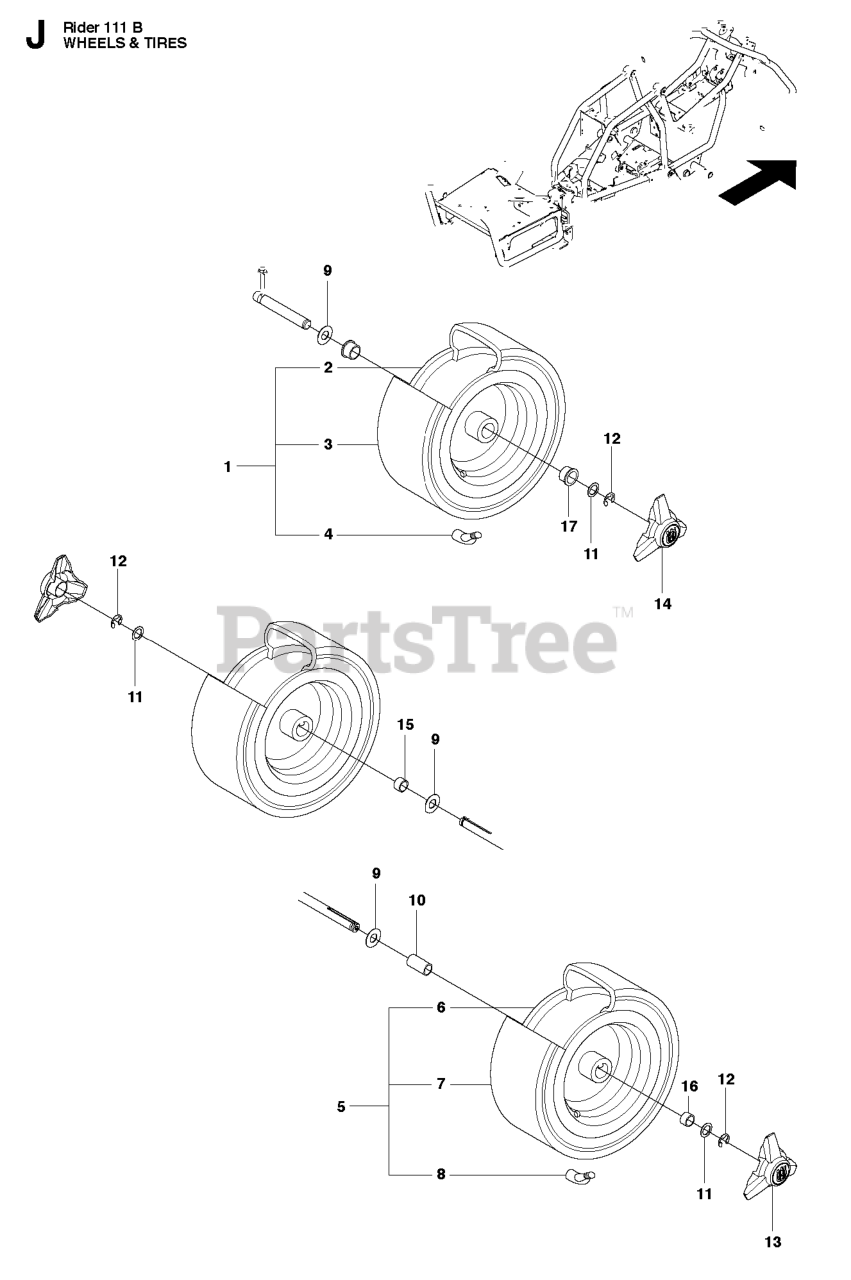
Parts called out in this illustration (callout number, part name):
4	VALVE
8	VALVE
12	RETAINING RING
